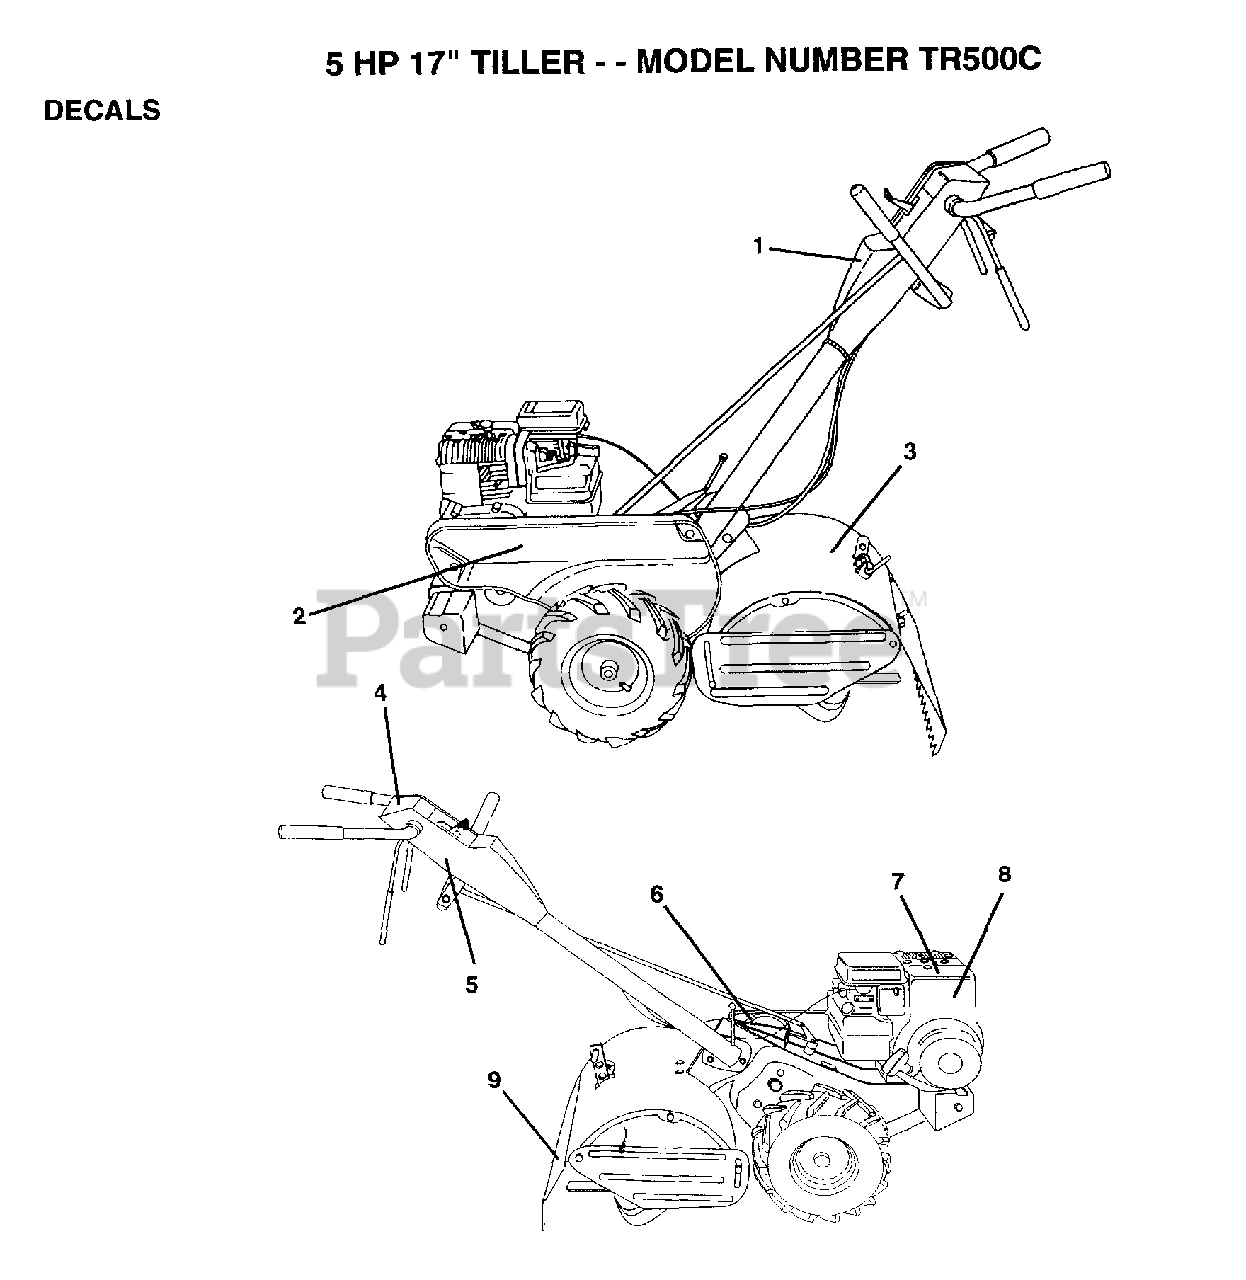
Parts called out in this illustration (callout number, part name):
1	DECAL.PNL.CONTROL
3	DECAL.SHLD.TINE
4	DECAL.INSTRUCTION
5	DECAL TI
6	DECAL CRT
9	DECAL TI
